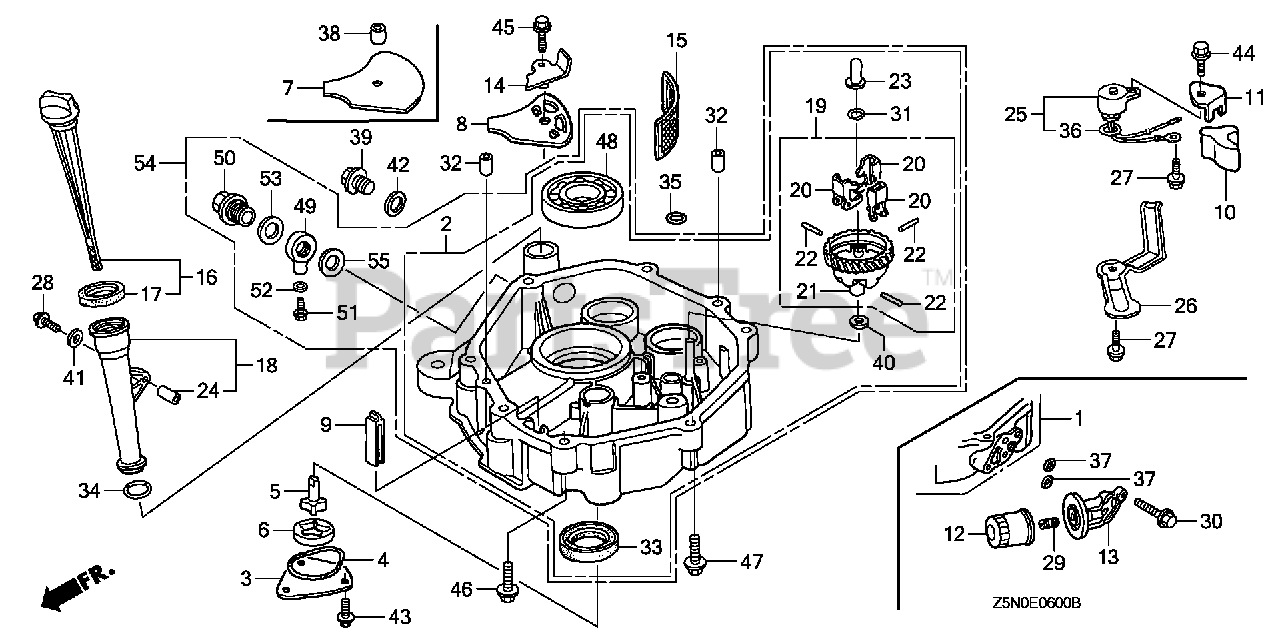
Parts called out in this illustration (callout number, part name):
1	PAN ASSY., OIL
3	COVER, OIL PUMP
4	O-RING, PUMP COVER
5	ROTOR (INNER)
6	ROTOR, OIL PUMP (OUTER)
8	PLATE, OIL FILTER
9	RUBBER, OIL RETURN
10	STOPPER, OIL
11	PLATE, OIL STOPPER
12	FILTER, OIL (FILTECH TOYO ROKI) (SOLD INDIVIDUALLY)
12	FILTER, OIL (TOYO ROKI) (SOLD INDIVIDUALLY)
13	BASE, OIL FILTER
14	PLATE, SUCTION
15	SCREEN, OIL FILTER
16	CAP ASSY., OIL FILLER
17	GASKET, OIL FILLER CAP
18	EXTENSION, OIL FILLER
19	GOVERNOR ASSY.
20	WEIGHT, GOVERNOR
21	HOLDER, GOVERNOR WEIGHT
22	PIN, GOVERNOR WEIGHT
23	SLIDER, GOVERNOR
24	COLLAR, EXTENSION
25	SWITCH, OIL LEVEL
26	PROTECTOR, SWITCH
27	BOLT, FLANGE (6X12) (CT200)
28	BOLT, FLANGE (6X35) (CT200)
29	HOLDER, OIL FILTER
30	BOLT, FLANGE (6X25) (CT200)
31	CLIP, GOVERNOR HOLDER
32	PIN, DOWEL (8X12)
33	OIL SEAL (35X52X8) (NOK)
34	O-RING (22.1X2.2)
35	O-RING (11.8X2.4)
36	O-RING (11.8X2.4)
37	O-RING (11X1.9) (NOK)
39	BOLT, DRAIN PLUG (20MM)
40	WASHER, PLAIN (6MM)
41	WASHER, PLAIN (6MM)
42	WASHER, DRAIN PLUG (20MM)
43	BOLT, FLANGE (6X12)
44	BOLT, FLANGE (6X16)
45	BOLT, FLANGE (6X25)
46	BOLT, FLANGE (8X40)
47	BOLT, FLANGE (8X60)
48	BEARING, RADIAL BALL (6207)
